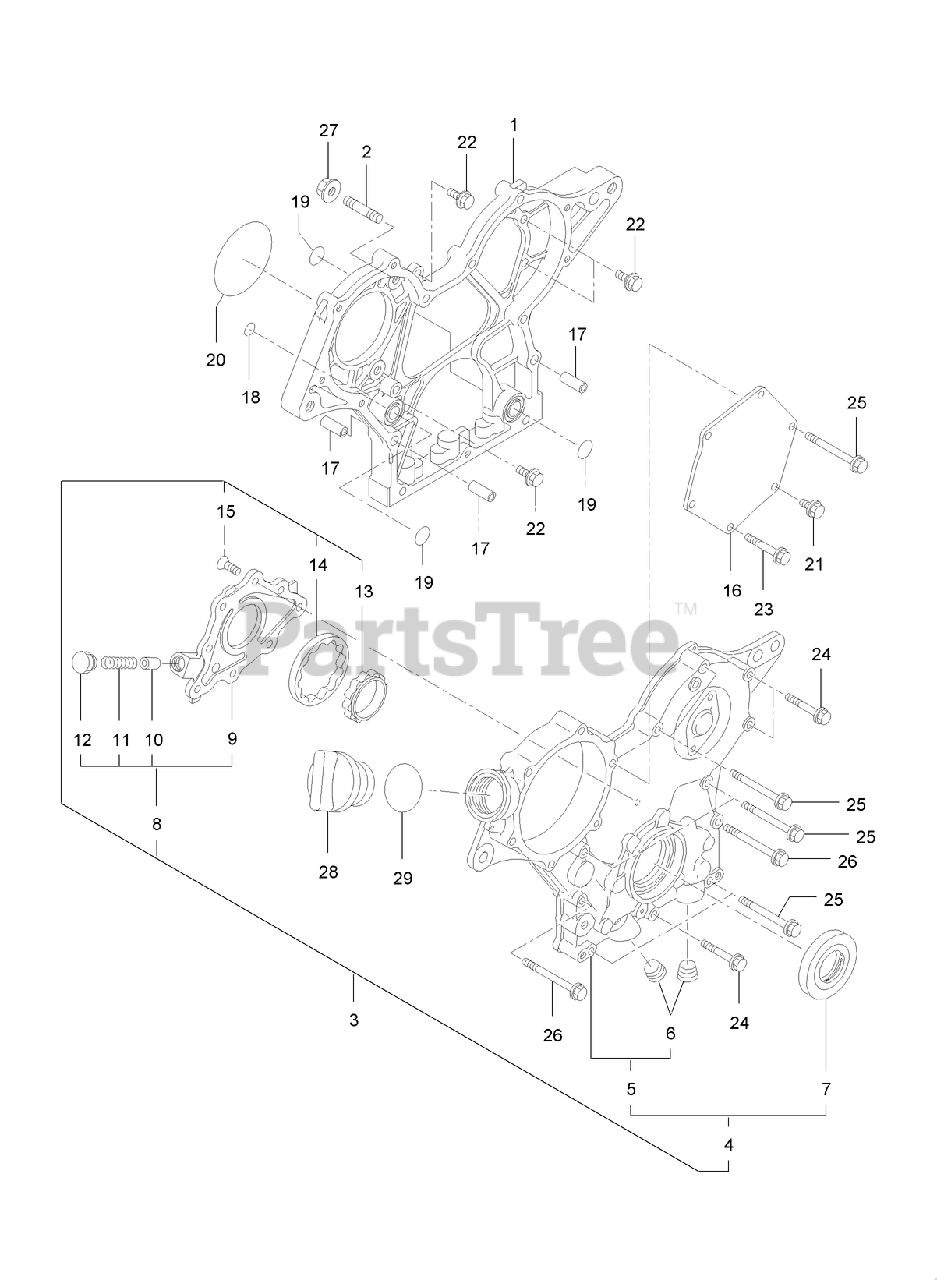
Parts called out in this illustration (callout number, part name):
1	CASE-GEAR
2	BOLT-STUD
3	COVER ASM-GEAR CASE
4	COVER ASSY-GEAR CASE
5	COVER-GEAR CASE
7	SEAL-OIL
8	COVER ASM
9	COVER-PUMP
10	VALVE-RELIEF
11	SPRING
13	ROTOR-INNER
14	ROTOR-OUTER
16	COVER-PUMP
17	PIPE-DOWEL
18	O-RING
19	O-RING
20	O-RING
28	COVER-FILLER
29	O-RING
